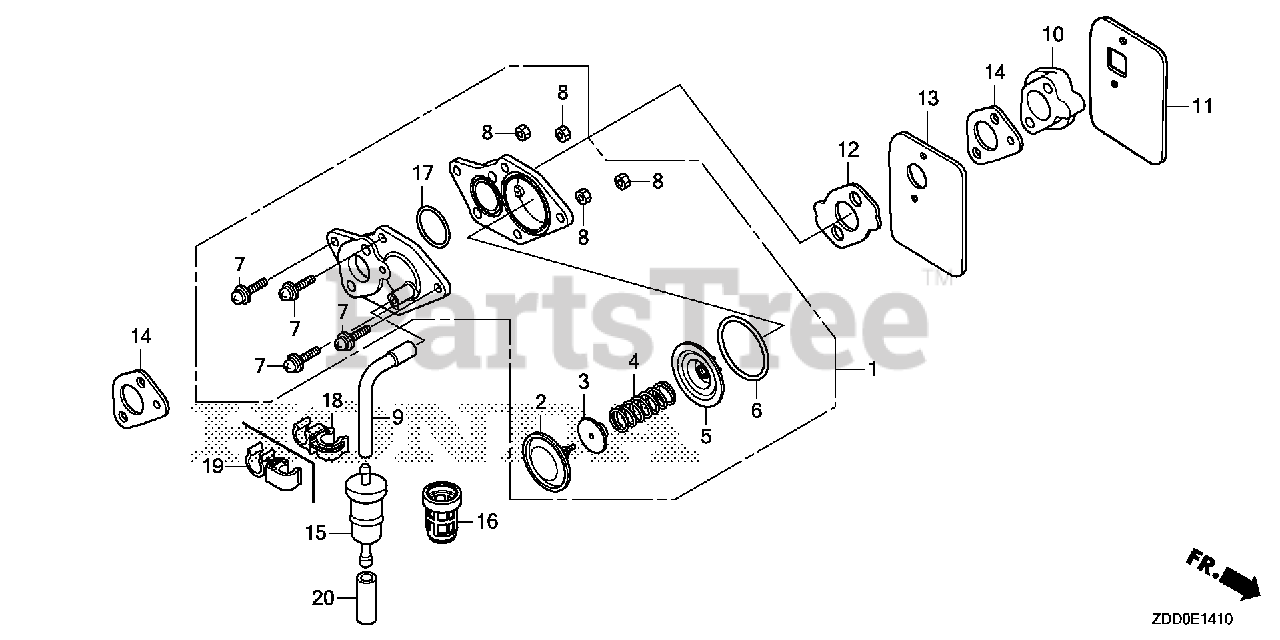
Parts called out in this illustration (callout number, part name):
1	PUMP ASSY., ACCELERATION
2	DIAPHRAGM, PUMP
3	RETAINER, DIAPHRAGM
5	RETAINER, ACCELERATION PUMP
7	SCREW ASSY.
9	TUBE, AIR VENT
10	INSULATOR, CARBURETOR
11	GASKET, INSULATOR
12	GASKET B, INSULATOR
13	PLATE, INSULATOR
14	GASKET, CARBURETOR
15	STRAINER, FUEL
16	SUSPENSION, STRAINER
17	O-RING (19.5X1.5)
18	CLIP, TUBE
20	BULK HOSE, VACUUM (7X3000) (7X550)
